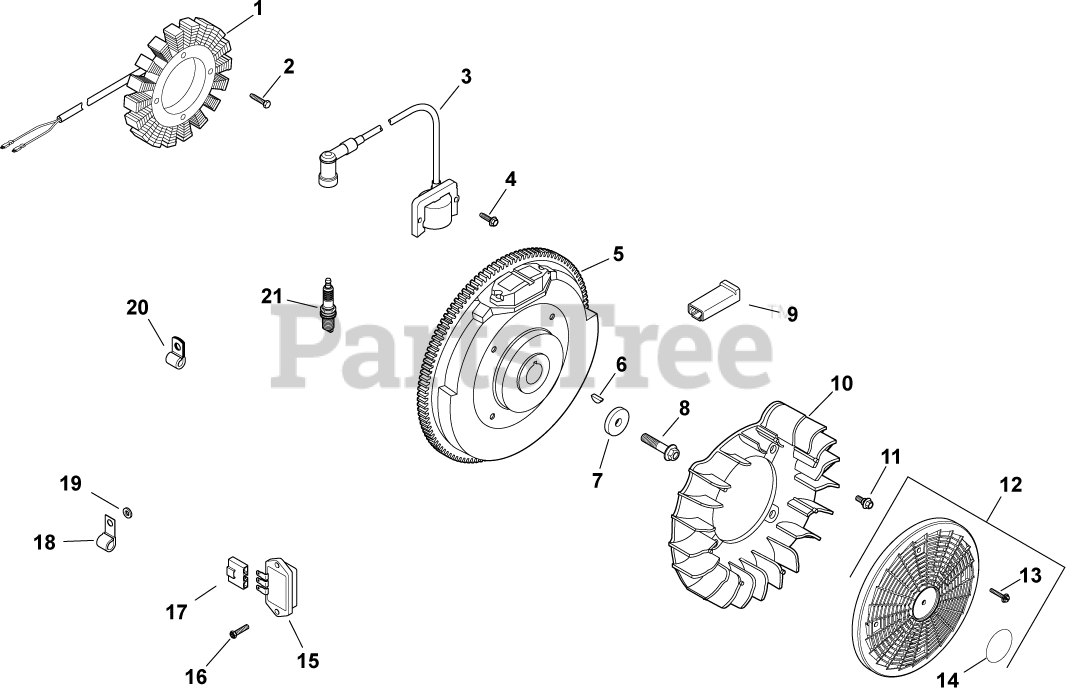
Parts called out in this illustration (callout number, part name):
1	KIT, 15 / 20 AMP STATOR
2	SCREW, M5X0.8X25 - (#25086402S)
3	KIT, MODULE IGNTN (CDI FIXED)
4	SCREW, FLG THD FRM M5X.8X20-(#25086399S)
5	FLYWHEEL ASSEMBLY
6	KEY, 3/16" X 5/8"
7	WASHER, FLAT 13/32"
8	SCREW, FLG M10X1.5X45 - (#25086361S)
9	CONNECTOR (1 CONTACT)
11	BOLT, SHOULDER
12	KIT, GRASS SCREEN
13	SCREW, FLG SEMS M4X.7X25
14	DECAL, GRASS SCREEN USE 24 113 499-S
15	REG/RECT-15 AMP (KM)-USE 41 403 10-S
16	SCREW, HEX FLANGE HI-LO
17	CONNECTOR, BODY (KM)-USE 25 155 41-S
18	CLIP, CABLE
19	WASHER, FLAT 1/4" (O.D. 1/2")
21	PLUG, SPARK (STD)
